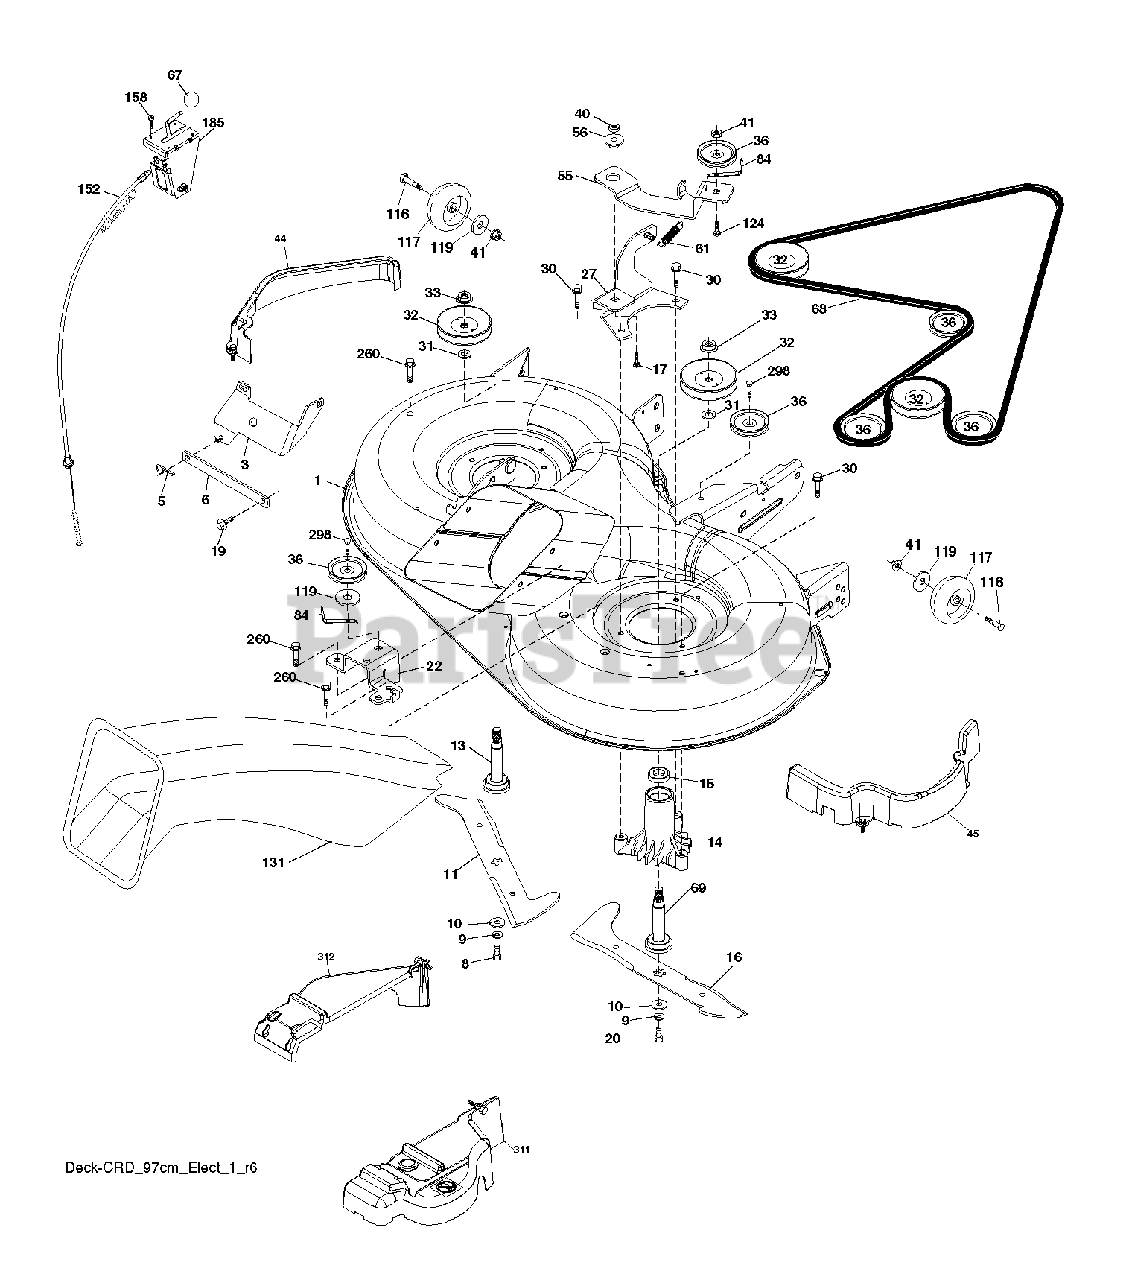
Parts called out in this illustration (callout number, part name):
3	BRACKET.ASM.BAR.SWAY.CHASS
5	RETAINER-SPRNG RB
6	BAR SWAY
9	LOCKWASHER
10	WASHER.BLADE
11	BLADE.3N1.LH.CRD.97
13	SHAFT ASM VENT
14	HSG MANDREL
16	BLADE.3N1.RH.CRD.97
17	BOLT.3/8-14X1.25
19	BOLT SHD 5/16-18
22	BRACKET.SUPT.IDLER.REAR.RH
27	BRACKET.ASM.SUSP.REAR.RH.
30	SCREW, WASHER HEAD
31	WASHER.SPACER.MANDREL
32	PULLEY MANDREL
33	NUT.FLANGE.LOCK.TOP
36	PULLEY.IDLER.4.25
40	LOCKNUT
41	NUT LOCK FLG 3/8-16 UNC
56	SPACER.RETAINER.MOWER
67	KNOB T (3/8 HOLE)
68	BELT.DRIVE.CRD.97.2010
69	SHAFT.ASM.W/LWR.BRG.RH.THREAD
84	KEEPER, BELT IDLER
116	BOLT.SHOULDER.3/8-16X3-5/8
117	WHEEL. GUAGE RALLY
124	BOLT.3/8-16X1.50
131	CHUTE BAGGER
158	SCREW
185	HEAD ASM. CABLE CLUTCH
260	SCREW 3/8-16X1/2
298	SCREW LT
